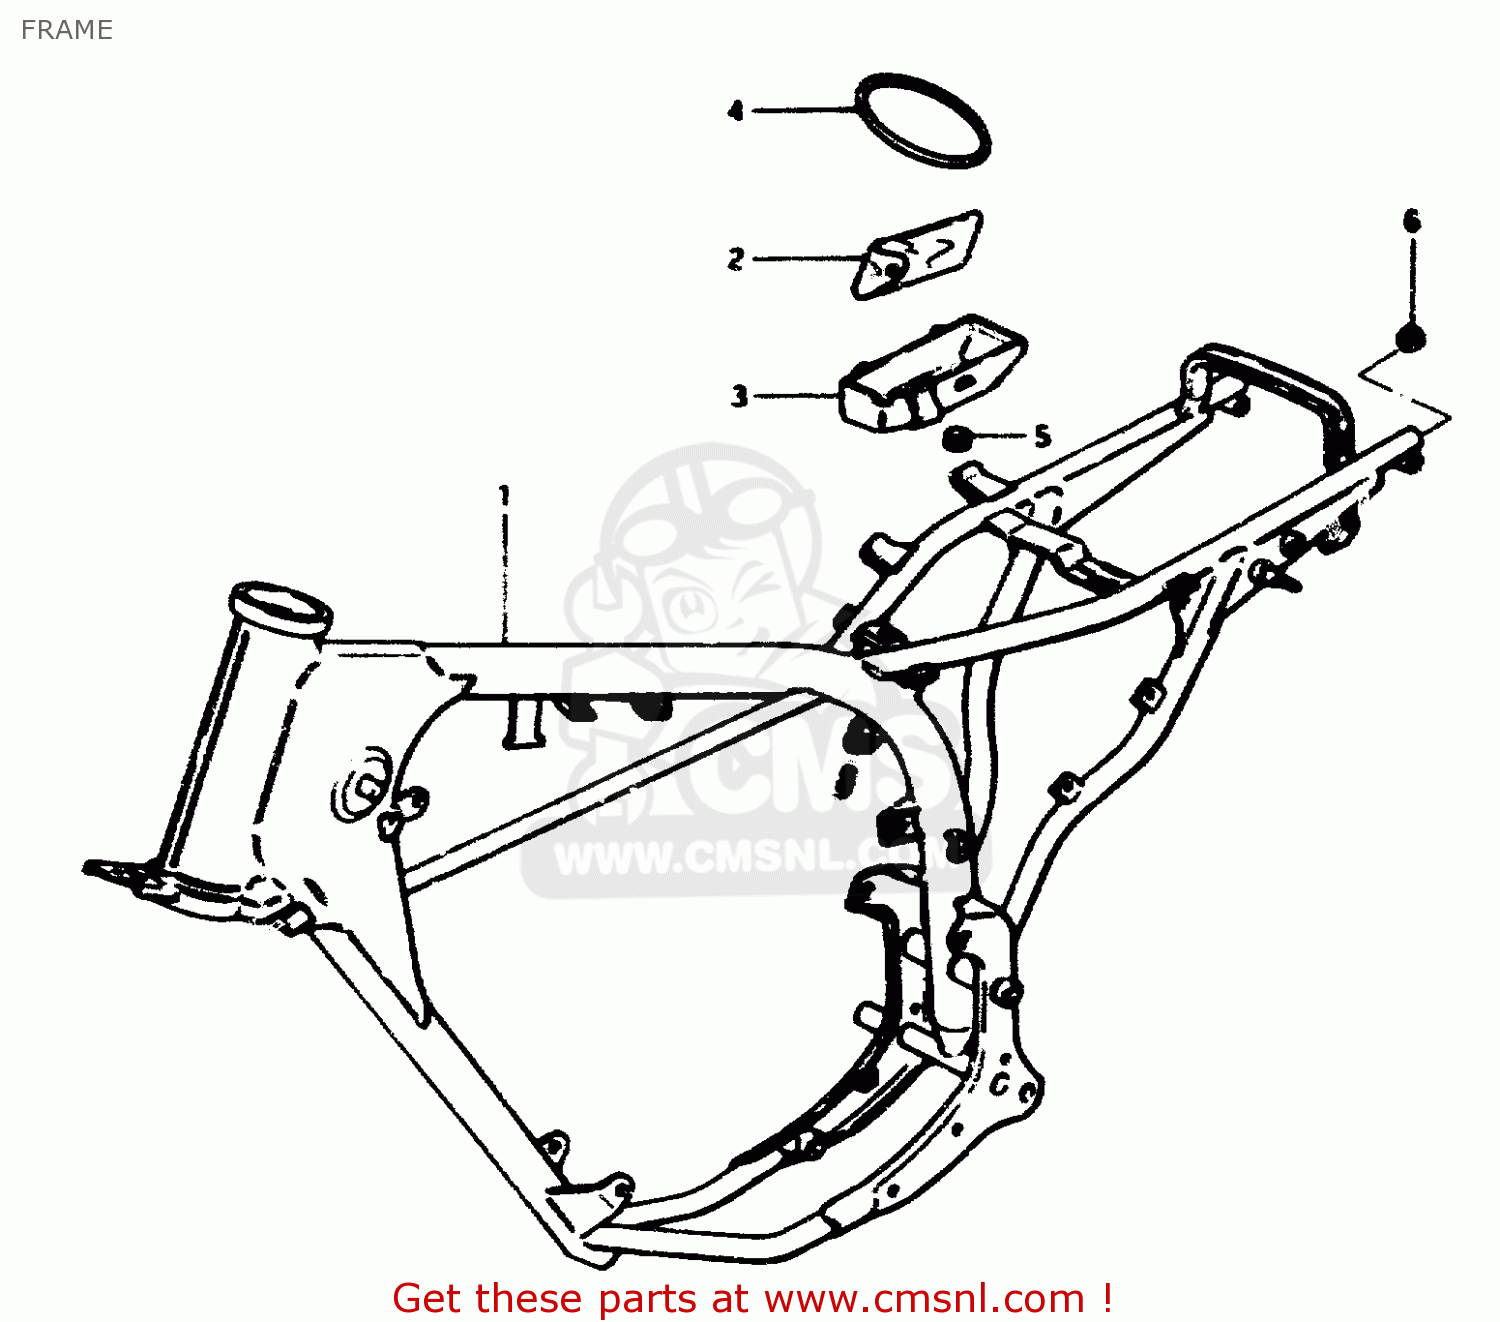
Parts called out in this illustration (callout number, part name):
1	FRAME (BLACK)
2	TOOL SET
3	HOLDER, TOOL
4	O RING(D:3.5,ID:76)
5	CUSHION
6	PLUG(OD:17)
